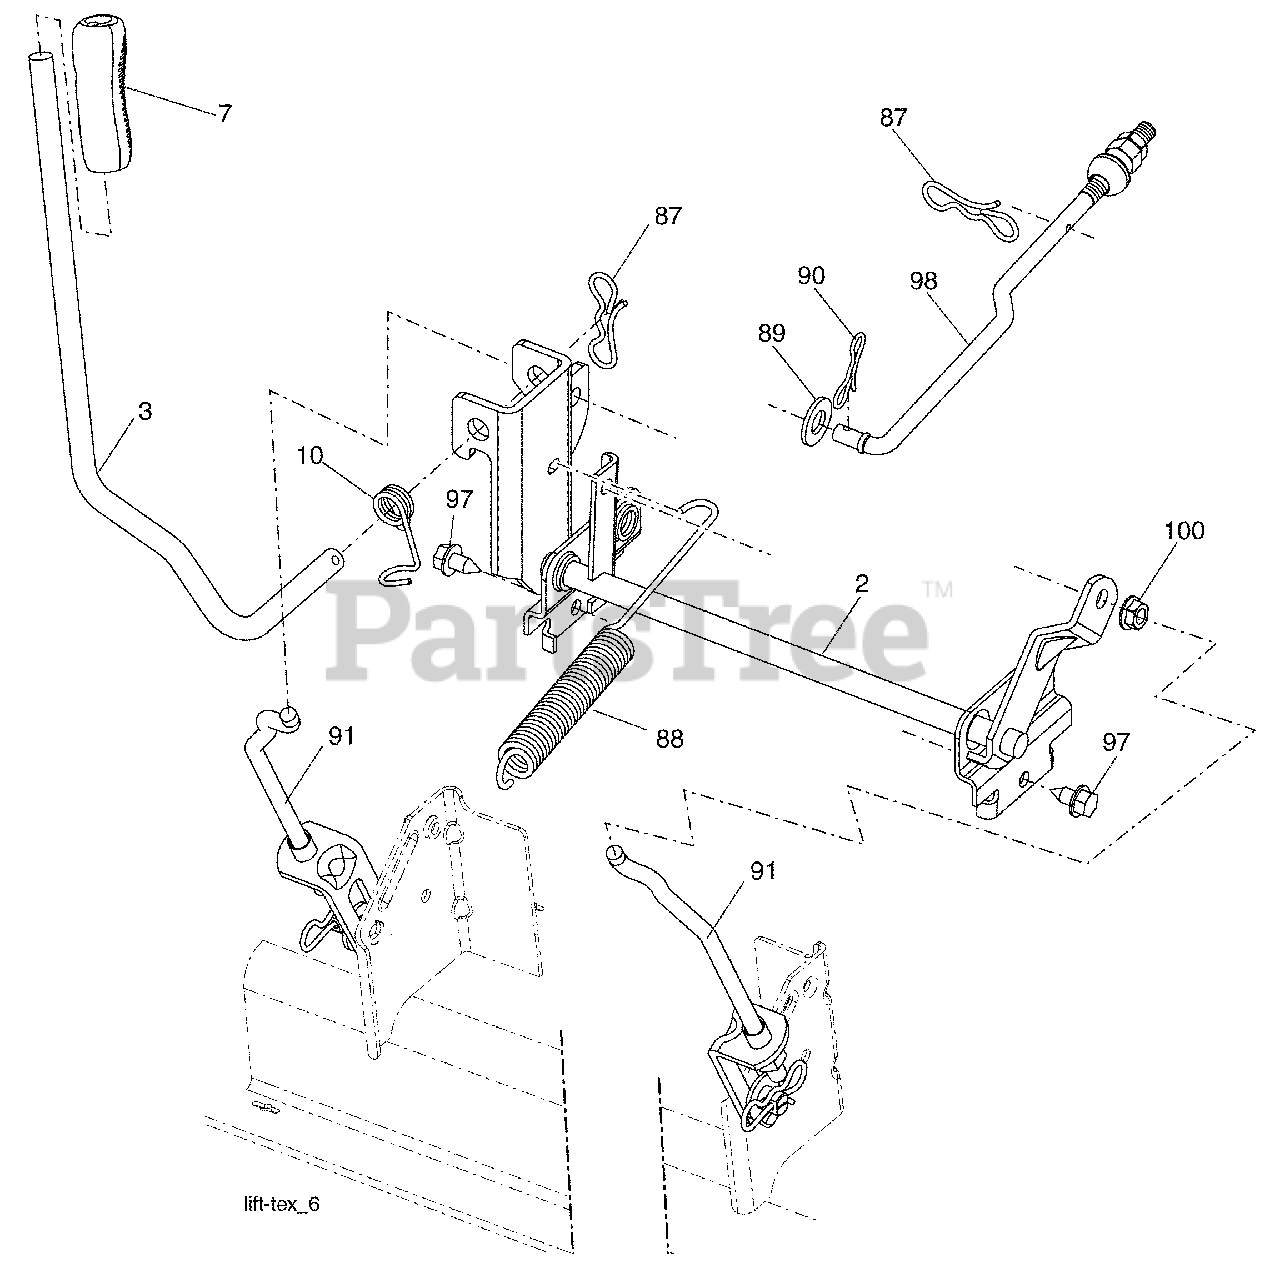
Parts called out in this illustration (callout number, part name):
2	Shaft Asm., Lift
3	Lever Asm., Lift Rh
7	Grip, Lever
10	Spring Torsion
87	Pin Cotter 7/16 Bow Tie Lock
88	Spring Lift Assist
89	Washer Clear Zinc
90	Pin Cotter 5/16 Bow Tie Lock
91	Link Asm Lift LH Rear
97	Screw Hex Wsh. THDR 3/8-16 x 3/4
98	Link Lift Susp. Front Mower
100	Nut Centerlock 3/8-16 unc
